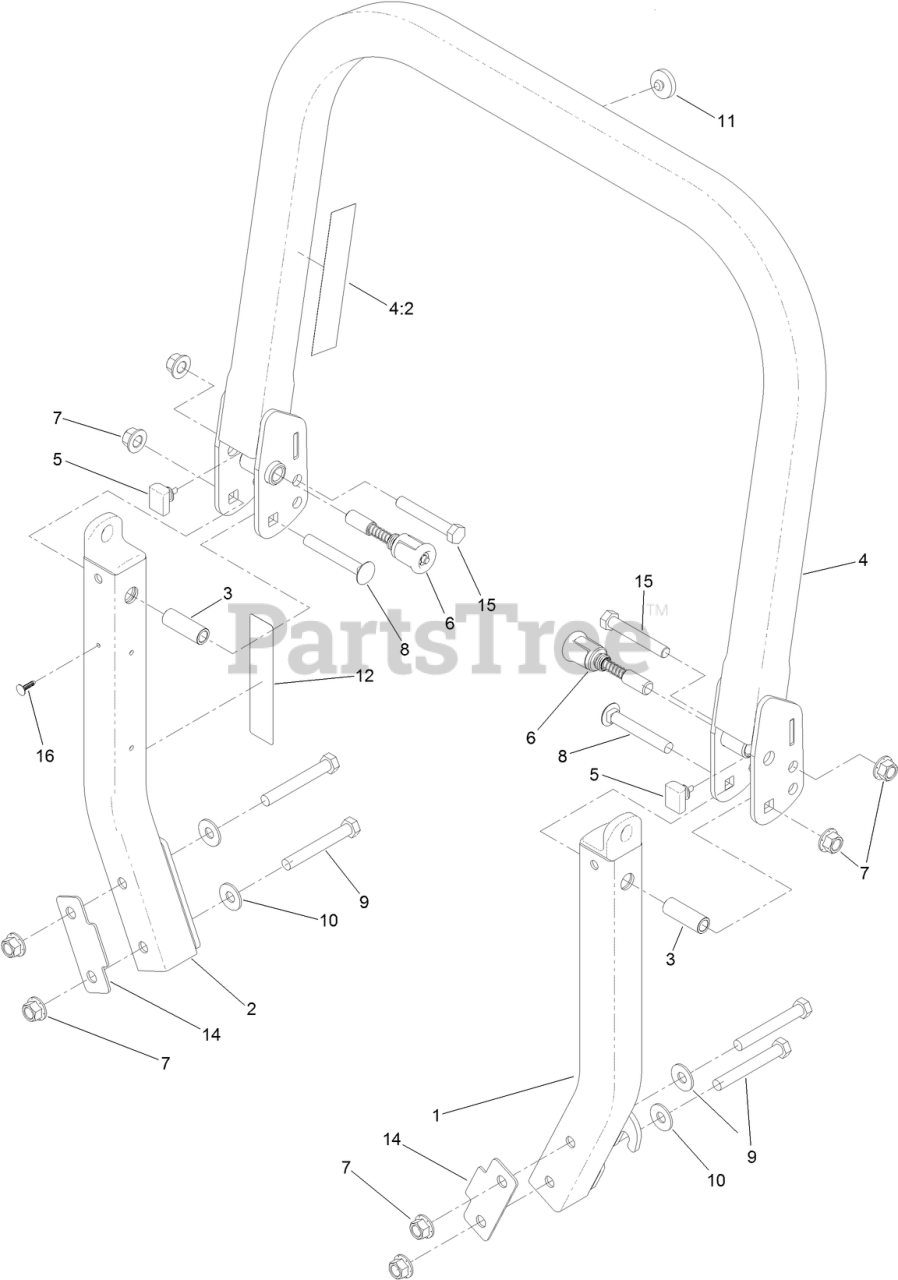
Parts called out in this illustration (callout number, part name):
1	LEG-ROPS, LH
2	LEG-ROPS, RH
3	SPACER
4	UPPER ROPS ASM
4:2	DECAL-WARNING
5	BUMPER-ROPS
6	PIN-SPRING
7	NUT-LOCK
8	SCREW-CARR
9	SCREW-HH
10	WASHER-SPRING
11	BUMPER-PUSH-IN, RUBBER
12	DECAL-CAUTION, FUEL VENT
14	SPACER
15	SCREW-HH
16	PLUG-PLASTIC
